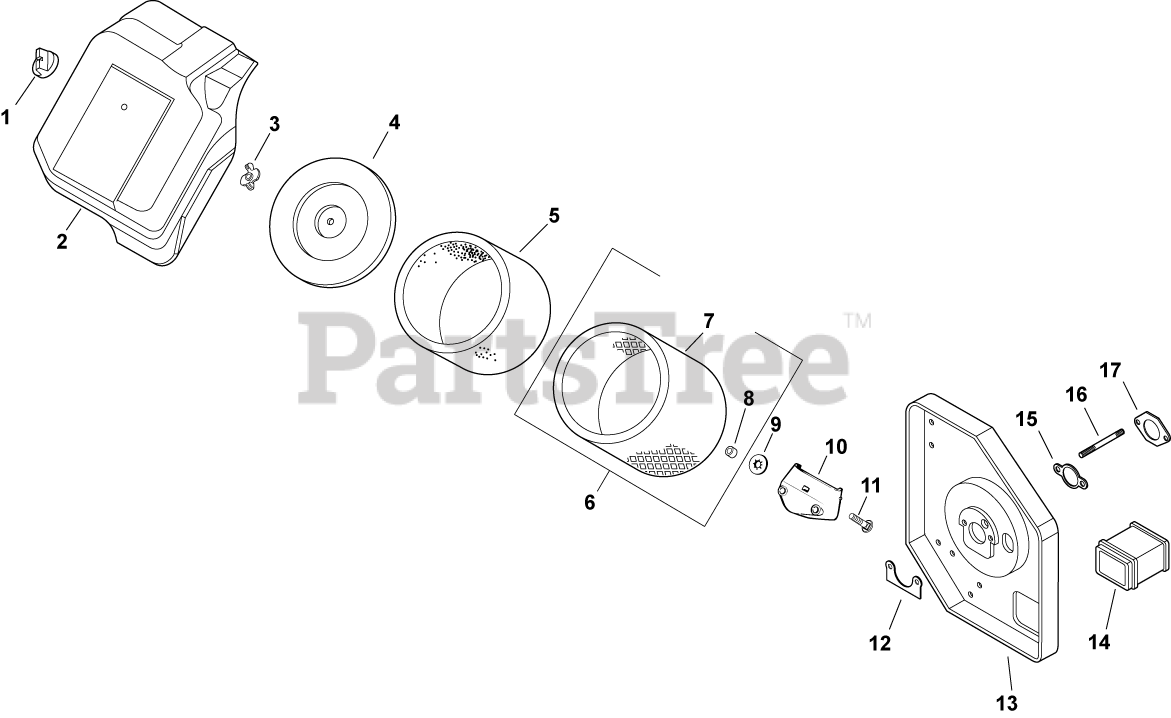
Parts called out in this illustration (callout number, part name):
1	KNOB, COVER
2	COVER, AIR CLEANER BASE
3	NUT, WING
4	COVER, AIR CLEANER
5	PRE-CLEANER
6	KIT, AIR CLEANER ELEMENT
7	ELEMENT, AIR CLEANER (KM) - Also available Retail Packaged 47 883 01-S1 Air Filter Kit
8	SEAL, INNER AIR CLEANER
9	RETAINER, RING
10	CUP, FUEL SPITBACK
12	GASKET, AIR CLEANER BASE
13	BASE, AIR CLEANER
15	GASKET, AIR CLEANER BASE
16	STUD,M6X1.0X116
17	GASKET, CARBURETOR
